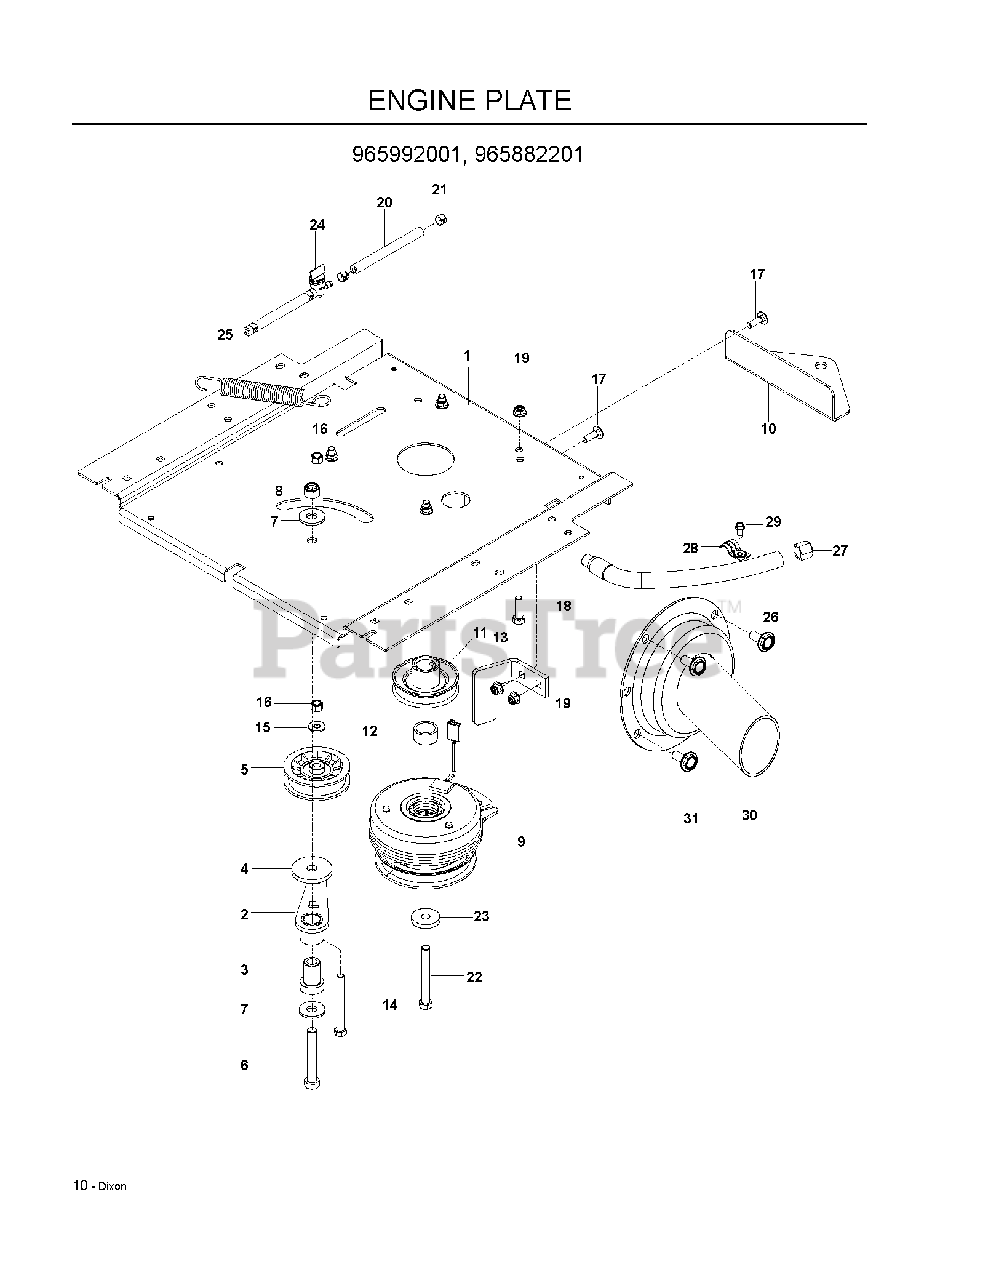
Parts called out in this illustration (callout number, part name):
1	PLATE ENGINE, BLACK
2	IDLER ARM WELDMENT
3	IDLER SPINDLE
4	HEAVY WASHER
5	PULLEY, IDLER
6	HCS 1/2C X 3 1/4
7	WASH USS FLAT 1/2
8	NUT 1/2-13 HEX NYLOC ZD
9	CLUTCH, 105 FT-LBS
10	HITCH, BLACK
11	PULLEY, ENGINE
12	T & B SPACER
13	STOP, CLUTCH, BLACK
14	HCS 3/8-16X3 1/2 GR5
15	WASHER 5/16 FLAT
16	NUT 3/8-16 NYLOC
17	RHSNB 5/16C X 1
18	CAPSCREW 5/16 X 1/1/2 HEX HEAD
19	5/16-18 NYLOC FLANGE NUT
20	FUEL LINE 5"
21	HOSE CLAMP
22	HCS 7/16-20X3-1/2 GR 5 ZN
23	CLUTCH, WASHER
24	FUEL VALVE
25	SPRING, DECK DRIVE
26	OIL DRAIN HOSE
27	DRAIN CAP
29	SCREW 1/4 X 5/8
30	MUFFLER EXTENSION
31	3/8-16X3/4 CARR BOLT
